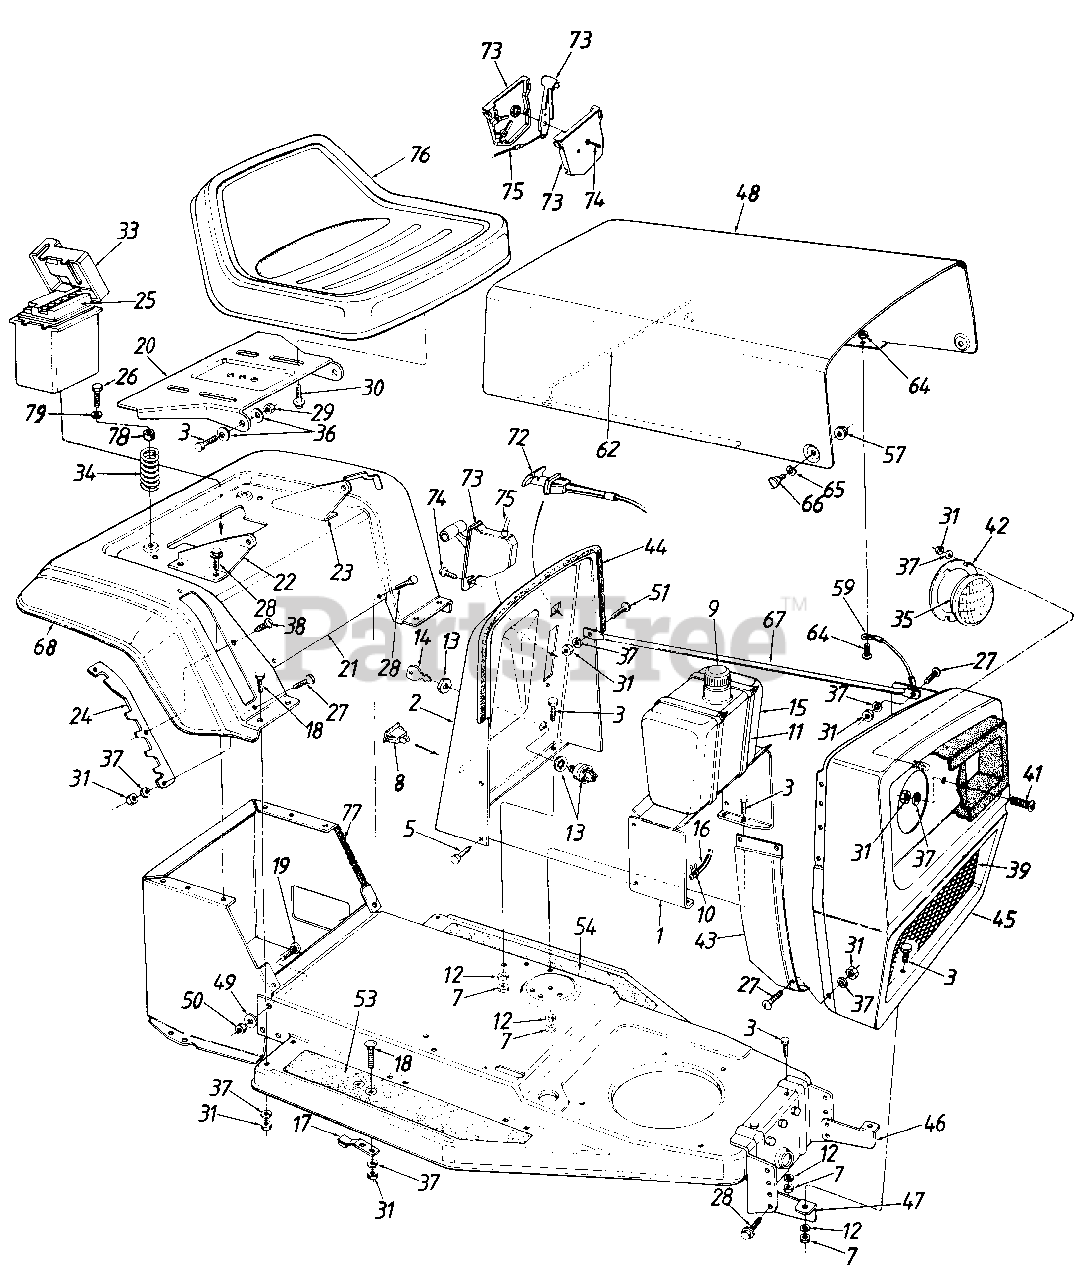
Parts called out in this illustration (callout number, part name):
1	Dash Panel Support Brkt.
5	Hex AB-Tap Scr. 1/4 x .62"
7	Hex Nut 5/16-18 Thd.
8	Light Switch
9	Gas Gauge
11	Cable Tie
12	L-Wash. 5116" I.D.
13	Ignition Switch
14	Ignition Key
15	Fuel Tank
16	Ga ne
17	Blade Brake Ass'y.
18	Carriage Bolt 1/4-20 x .62"
19	Ribbed Neck Bolt 3/8-24 x .8"
20	Seat Pivot Brkt.
21	Rear Fender
22	Seat Hinge Support Brkt.-R.H.
23	Seat Hinge Support Brkt.-L.H.
24	Deck Lift Index Brkt.
25	Battery
26	Hex Self-Tap Screw 5/6-18 x 1" Lg.
27	Truss Mach. Scr. 1/4-20 x .75" Lg.
28	Hex AB-Tap Scr. 5/16 x .75" Lg.
29	Hex L-Nut 5/16-18 Thd.
30	Hex Self-Tap Scr. 3/8-16 x .75" Lg.
31	Hex Nut 1/4-20 Thd.
33	Battery Box w/Cover
34	Compression Spring
35	Headlight
36	Bell-Wash. 5/16" I.D.
37	L-Wash. 1/4" I.D.
38	Hex Wash. Hd. Self-Tap Scr. #10 x .5" Lg.
39	Grille Insert
41	C-Sunk Mach. Scr. 1/4-20 x 1.5"
42	Headlight Retainer
43	Side Panel-R.H.
44	Trim Strip 26l/2n Lg.
46	Grille Mtg. Brkt.-L.H.
47	Grille Mtg. Brkt.-R.H.
50	Hex L-Nut 3/8-24 Thd.
51	Hex Bolt 1/4-20 x .62" Lg.
53	Foot Pad-R.H.
54	Foot Pad-L.H.
57	Lock Nut 1/4-28 Thd.
64	Hex Sems Nut #10-24 Thd.
65	Spr. Wash. .39" I.D. x .62" O.D.
66	Shld. Bolt
67	Grille Support
68	Trim Strip 79" Lg.
72	Choke Control
73	Throttle Control Box
74	Truss AB-Tap Scr. #10 x .5"
75	Throttle Wire
76	Seat Asse-nbly
77	Trim Strip 5" Lg.
78	Rubber Washer
79	Flat Wash. .344" I.D. x .88" O.D.
